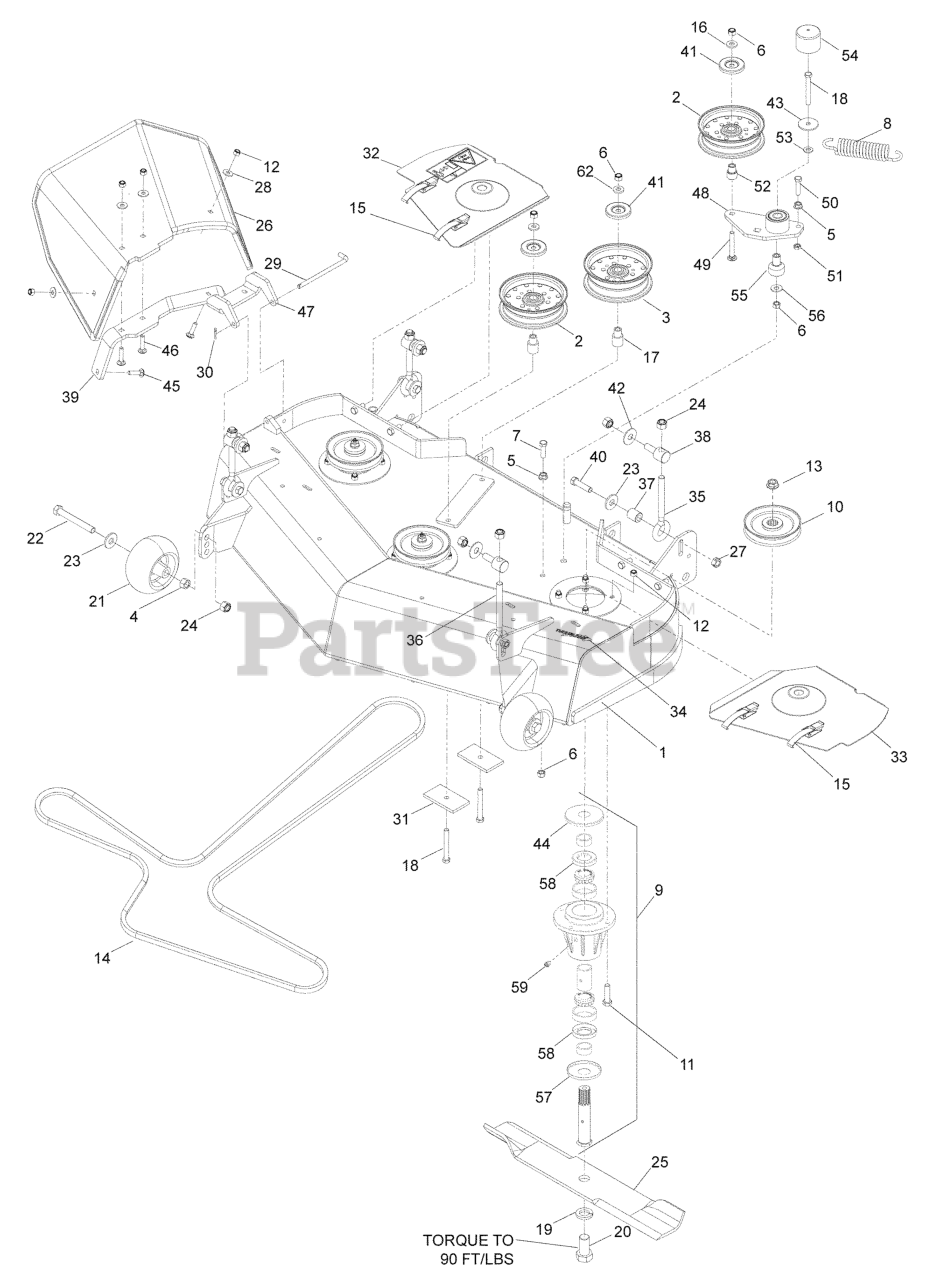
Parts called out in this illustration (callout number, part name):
1	DECK W/DECALS 42"
2	IDLER PULLEY
3	IDLER PULLEY (TALL)
4	NUT HEX 1/2
5	NUT 3/8C WHIZ
6	NUT 3/8-16 NYLOC
7	HCS 3/8C X 1 1/4 GR5
9	HOUSING ASM, 52/61
10	PULLEY 42-48
11	HCS 5/16C X 1 1/4
12	NUT 5/16 NYLOC
13	NUT FLANGE 3/4-16
14	BELT, DECK
15	DRAW LATCH
16	WASHER, 3/8 THICK
17	IDLER BUSHING
18	HCS 3/8C X 3
19	LOCKWASHER 5/8
20	HCS 5/8F X 1 1/4
21	GAUGE WHEEL
22	HCS 1/2-13 X 4 GR 5 ZD
23	WASH USS FLAT 1/2
24	NUT 1/2-13 HEX NYLOC ZD
25	BLADE 14-5/8" TUNNEL RAM
26	CHUTE, RUBBER DISCHARGE 42/48"
27	NUT 7/16C CENTERLOCK
28	WASHER 5/16 FLAT
29	PIN, CHUTE PIVOT
30	RP_COTTER PIN 1/8 X 3/4
31	SUPPORT PLATE
32	BELT SHIELD ASM RH
33	BELT SHIELD ASM LH
34	DECAL, TUNNEL RAM 4"
36	EYEBOLT, 1/2-13 X 5.88
38	SWIVEL, DECK HEIGHT ADJ
39	BRACKET, REINF-CHUTE
40	HCS 7/16 - 14 X 1 3/4
41	DUST SHIELD
42	WASHER-.533IDX1.37OD
43	WASHER, 3/8 SPEC
44	TOP DUST CAP
45	BOLT, CARRIAGE 5/16X1-1/4
46	RHSNB 5/16-18 X 1-1/2 GR 5 ZD
47	PIVOT BRACKET - RUBBER CHUTE
48	ARM-IDLER W/BRG
49	RHSNB 3/8-16 X 2.75
50	HCS 3/8-16 X 1-1/2
51	NUT 3/8-16 HEX JAM
52	BUSHING, IDLER
53	WASHER 3/8 SAE FLAT
54	CAP, VINYL
55	PIVOT, BEARING
56	WASHER 3/8 FLAT
57	BOTTOM DUST CAP
58	SHAFT SEAL
59	PLUG-VENTED
